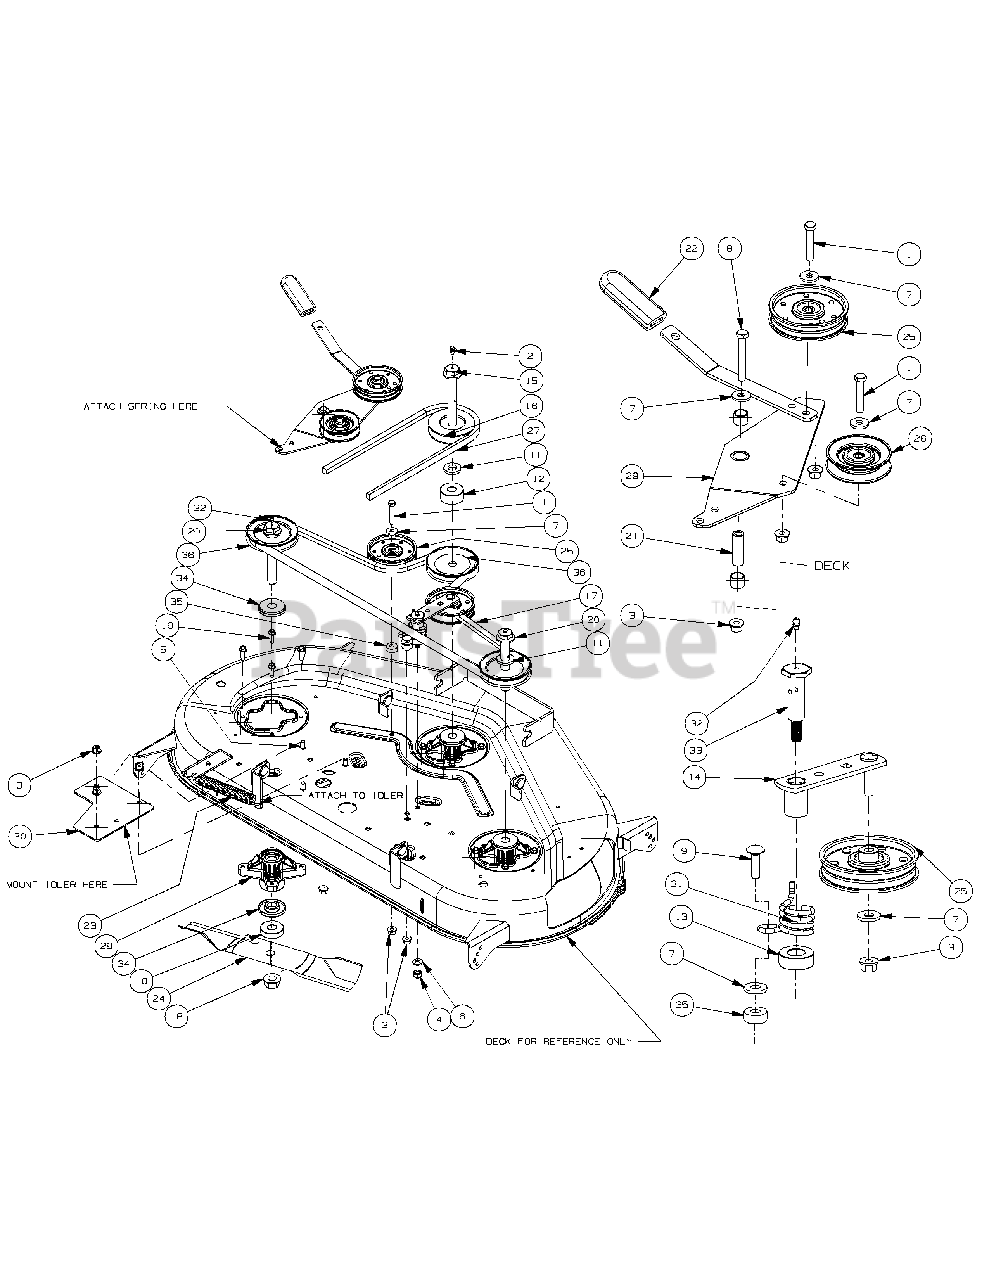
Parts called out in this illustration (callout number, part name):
1	Hex Cap Screw 3/8-16 x 2.00
2	Grease Fitting, 1/4-28, 90 degree
3	Hex Nut, 3/8-16, Flange Lock
4	Nut 7/16-14, Nylock
5	Carriage Bolt, 3/8-16 x .75
6	Flat Washer, .469 ID x .875 OD x .105
7	Flat Washer, .406 ID x 1.0 OD x .105
8	HHCS, 3/8-16 x 2.75
9	Carraige Screw, 3/8-16 x 1.25
10	Spacer, .76 ID x 2.00 OD x .477
11	Spacer .812 ID x .218
12	Spacer, .760 ID x 2.000 OD x 1.1
13	Spacer .760 ID x 1.5 OD
14	Idler Arm Assembly
15	Spindle Bolt 3/4-16 x 7.155
16	V-Pulley 4.25 OD Casting
17	V-Belt, A-Section
18	Nut, 3/4-16, Hex Flange
19	Self Tapping Screw 5/16-18 x 1.0
20	Spindle Bolt 3/4-16 x 5.37
21	Spacer, .39 ID x .625 OD x 1.875
22	Parking Brake Grip
23	Extension Spring, .94 OD x 7.72 LG
25	Flat Pulley
26	Idler Pulley, 3.50 Dia.
27	V-Belt, B-Section
28	Spindle Assembly
29	Idler Arm Assembly, Double, includes:
32	Grease Fitting
33	Shoulder Screw .68 x 2.11
34	Spindle Spacer
35	Spacer .406 ID x 1.0 OD
